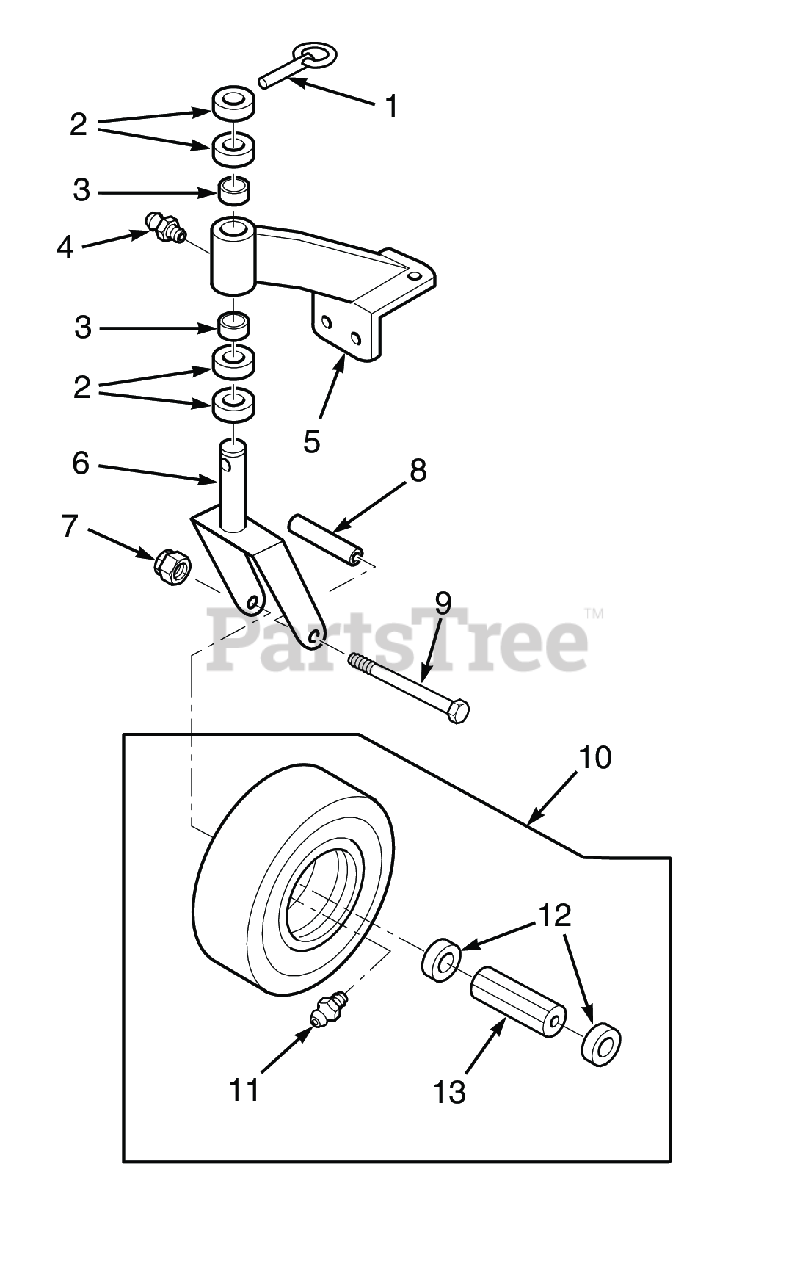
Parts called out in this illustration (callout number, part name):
1	Quick Pin, .438" Dia.
2	SPACER, CASTER YOKE, 1/2" THICK
3	Bronze Bushing, 7/8 ID x 1.0 Flanged
4	GREASE FITTING, STR. 1/4-28 SELF TAP.
5	SUPPORT ASSEMBLY(INCLUDES ITEMS 21, 82).
6	Caster Yoke Weldment
7	HEX LOCKNUT, ELASTIC STOP, 1/2-13
8	SLEEVE, CASTER WHEEL BEARING
9	Bolt, Hex Head 1/2-13 x 5-1/2" (Three Weights Installed)
11	GREASE FITTING, 45 DEGREE 1/4-28
12	Retainer, Bearing, Caster Wheel
13	Roller Bearing, .625 x 3-1/4"
